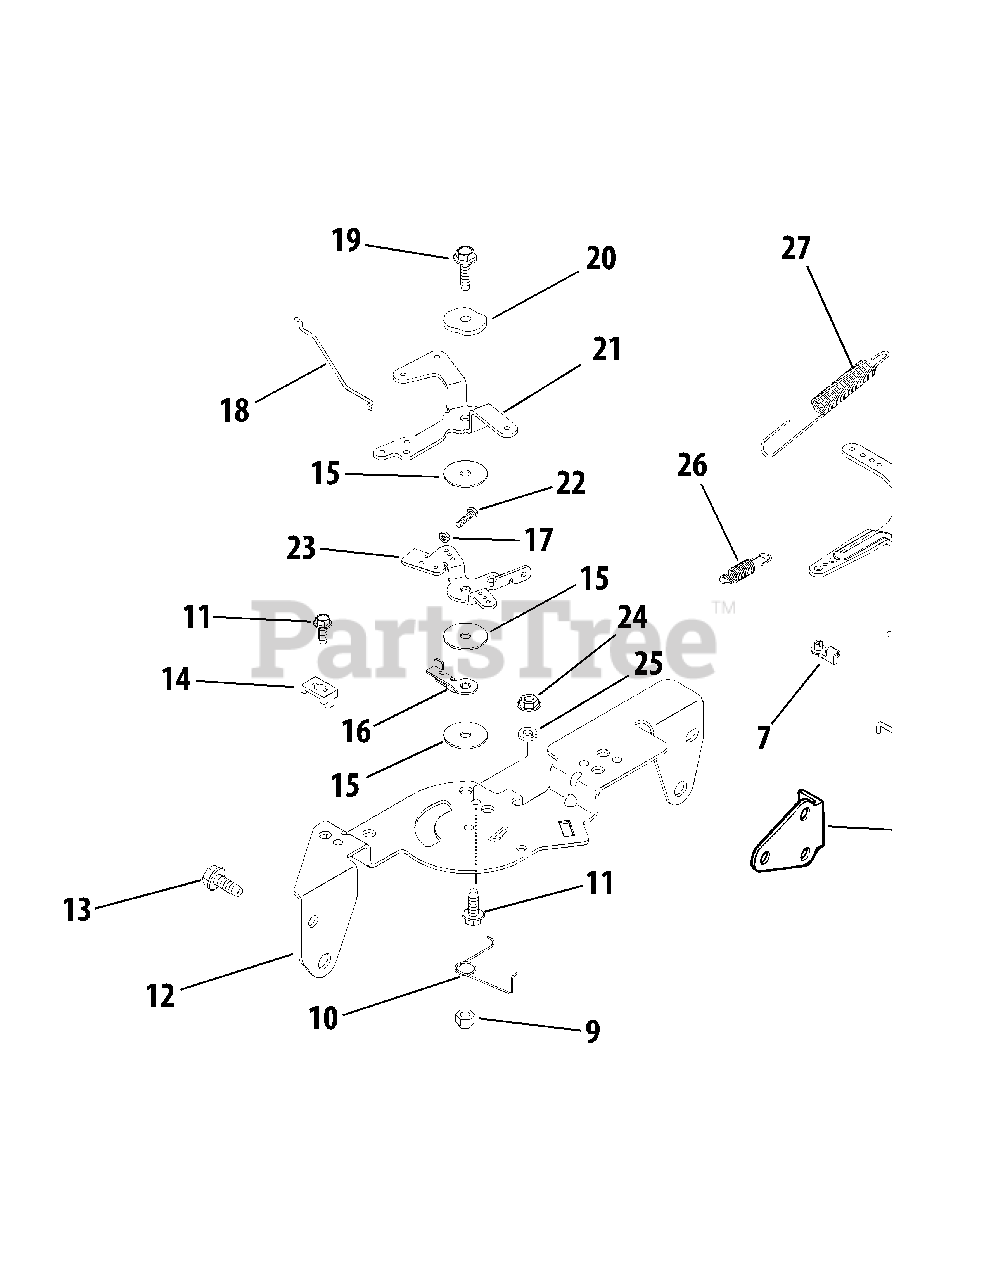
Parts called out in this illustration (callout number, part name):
1	Screw, Round Hd. Square Neck
2	Lever, Governor
3	Nut, Hex Flange M6 x 1.0
4	Spring, Linkage
5	Bushing, Linkage Retaining
6	Linkage, Throttle
7	Bushing, Linkage Retaining
8	Bracket, Support
9	Nut, Hex Lock M5 x 0.8
10	Spring, Choke Return
11	Screw, Hex Flange M5 x 0.8 x 16
12	Bracket, Control
13	Screw, Hex Flange M6 x 1.0 x 16
14	Clamp, Cable
15	Washer , Plain 5.5mm
16	Lever, Throttle Actuator
17	Nut, Hex M4 x 0.7
18	Linkage, Choke
19	Screw, Hex Flange M5 x 0,.8 x 20
20	Washer, Spring 1/4"
21	Lever, Choke
22	Screw, Hex Cap M4 x 0.7 x30
23	Lever, Throttle Control
26	Spring, Governor
27	Spring, Throttle Limiter
